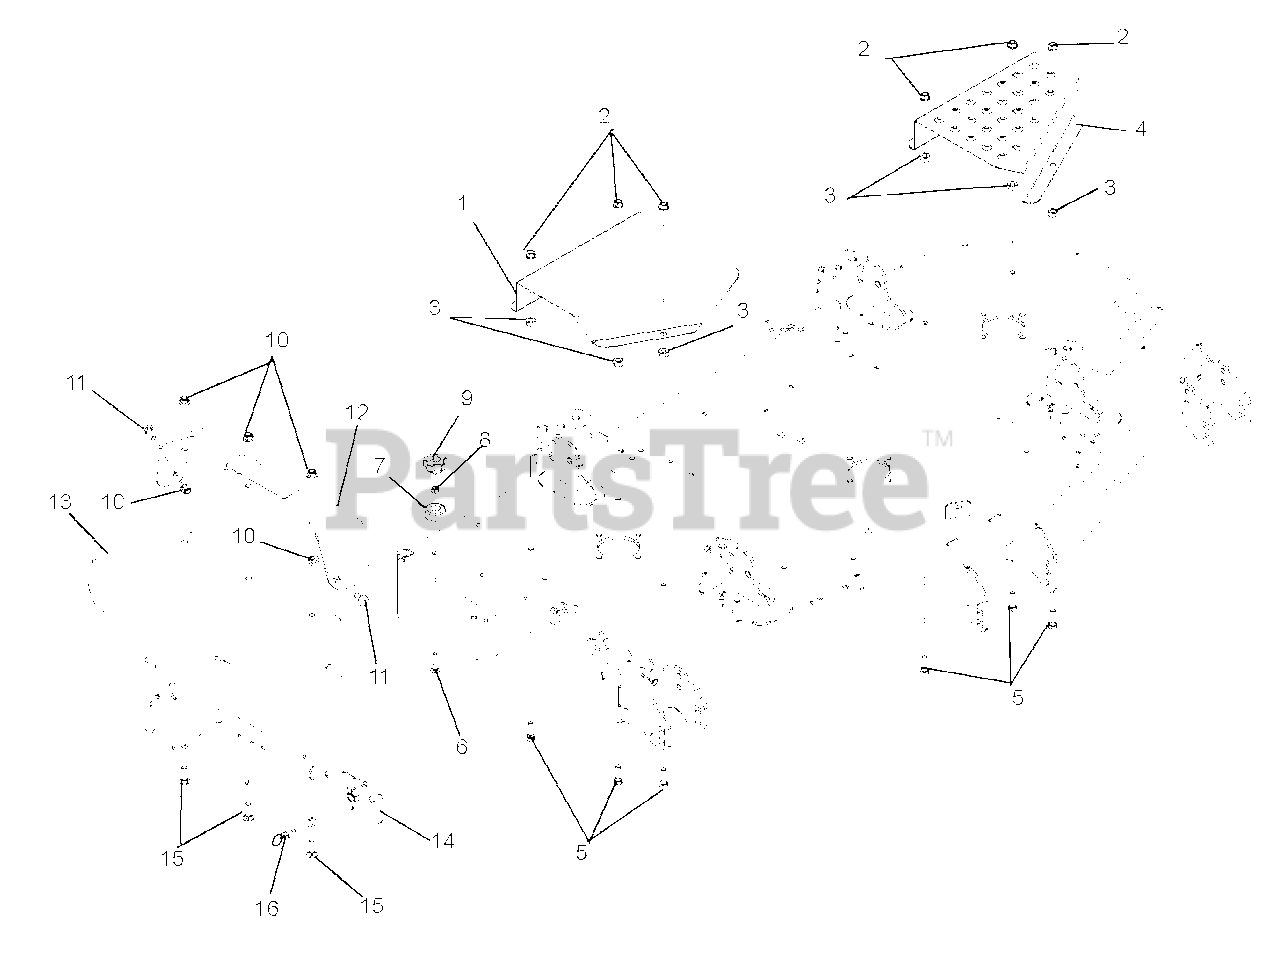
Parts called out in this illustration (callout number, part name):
1	Guard, Deck Belt, Right Hand 60" (992201, 203, 204, 198)
2	Nut, Spin Lock-Flange .375-16
3	Nut, Heavy Hex .38-16
4	Guard, Deck Belt, Left Hand 60" (992201, 203, 204, 198)
5	Bolt, Hex .38-16 x 1.25 Grade 5
6	Bolt, Round Head Square Neck .31-18 x 1.50 Grade 5
8	Nut, Locking-Center .31-18
9	Knob, Clamping, .312-18 Nyloc
10	Nut, Locking Nyloc Flange .38-16
11	Bolt, Round Head Square Neck .38-16 x 1.00 Grade 5
12	Support, Rubber Discharge Chute
13	Chute, Rubber Discharge
14	Discharge Chute Mounting Weldment (992200, 201, 203, 204, 205, 197, 198)
15	Bolt, Round Head Square Neck .38-16 x 1.25 Grade 5
16	Pull Pin, .50-13 Thread x .310 Diameter Plunger
